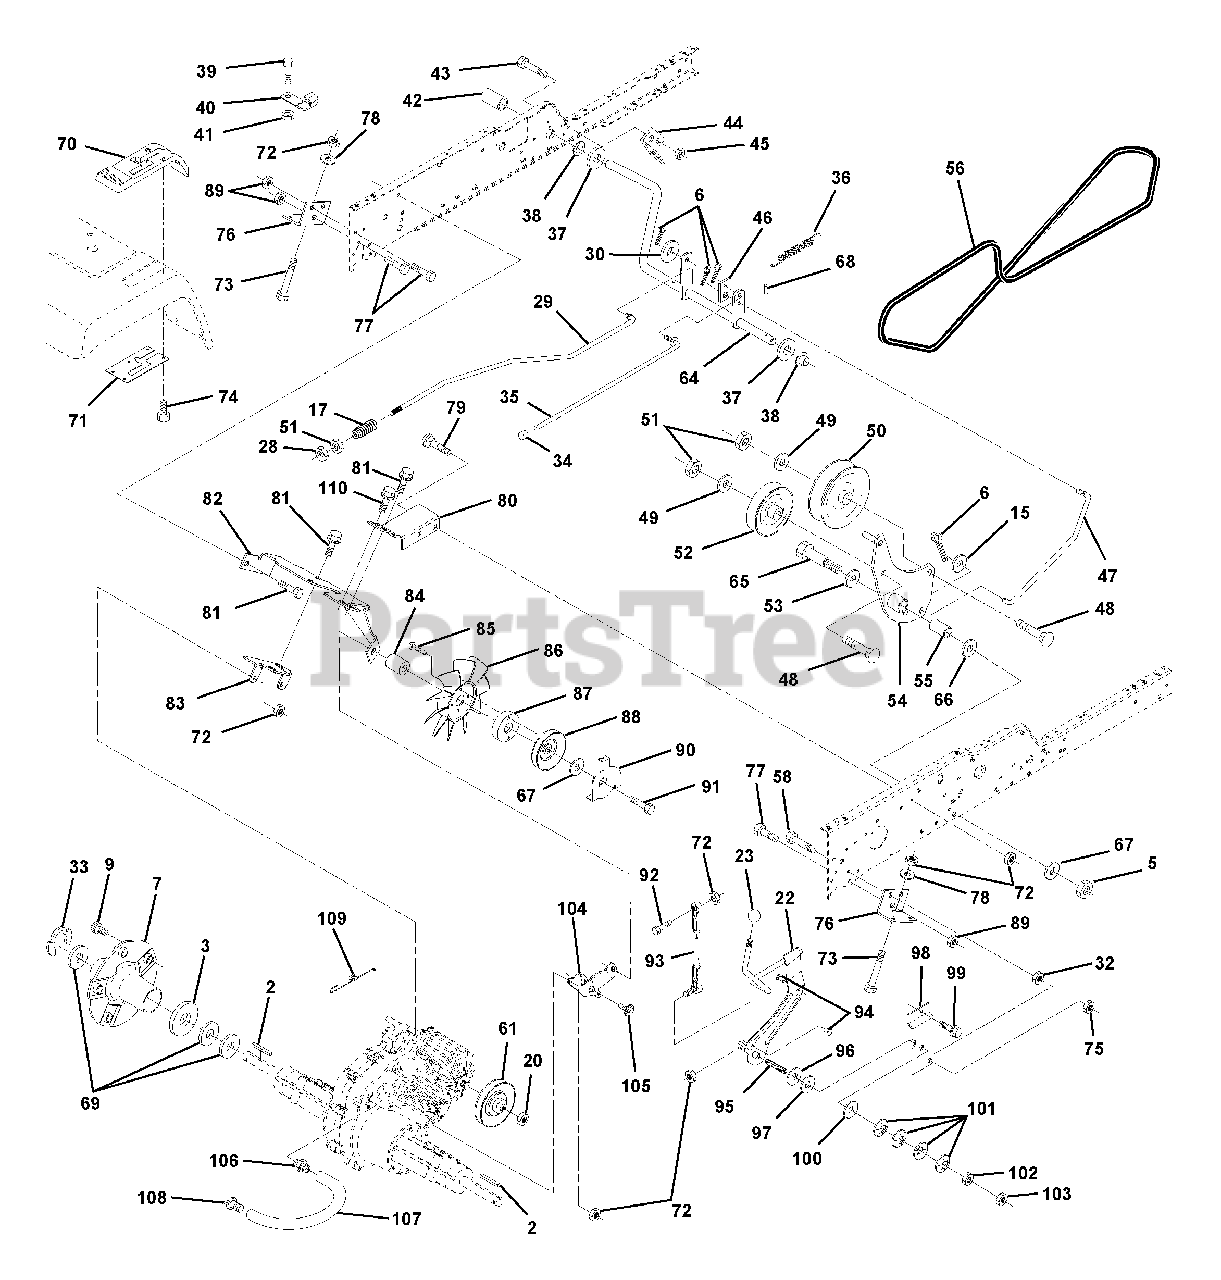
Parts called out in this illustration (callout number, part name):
2	Key 1/4 x 2.5
3	Washer Thrust Axle Harden
5	Nut Crownlock 3/8-16
6	Pin Cotter 1/8 x 3/4
7	Wheel Hub Asm.
9	Bolt Hub
15	Washer 13/32 x 13/16 x 16 Ga.
17	Spring Rod Brake
20	Nut Hex Jam Toplock 1/2-20
22	Shaft Arm Asm
28	Nut, Hex Jam 3/8-16
30	Washer 13/32 x 1 x 16 Ga
32	Nut Hex 7/16-14
34	Cap Plunger
35	Rod Parking Brake
36	Spring Drive Ground
37	Washer 25/32 x 1-1/4 x 16 Ga.
39	Screw Fin #10-24 x 1
40	Actuator Interlock Switch
41	Nut Lock #10-24
42	Cover Pedal
43	Bolt Hex Head 1/4-20 x 3/4
44	Bracket Interlock
45	Nut Lock W/Insert 1/4-20
46	Retainer Spring
47	Clutch Rod
48	Bolt Carriage 3/8-16 x 1-3/4 Gr. 5
49	Washer 13/32 x 7/8 x 13 Ga
50	Pulley Idler Flat
51	Nut Lock Hex 3/8-16
52	Pulley Idler Grooved
53	Washer Hartdened
54	Clutch Arm Asm
55	Bearing, Idler
58	Bolt Fin Hex 7/16-14 x 1-1/2
61	Pullery Transaxle
64	Shaft Asm Brake Parking Clutch
65	Bolt Shoulder
66	Washer Hardened
67	Washer 13/32 x 13/16 x 12 Ga
70	Console Hydro Fender
71	Plate Console Shift
72	Locknut Hex W/Washer Insert
73	Bolt Fin Hex 5/16-18 x 3
74	Screw, Hex Wsh Hi-Lo 1/4-1/2
75	Nut Lock Hex 7/16
76	Bracket Transaxle
77	Bolt Fin Hex 7/16-14 x 1
78	Washer 11/32 x 3/4 x 12 Ga.
79	Bolt Carriage 5/16-18 x 5/8
80	Bracket Torque RH
81	Screw Thdrol 3/8-16 x 3/4
82	Bracket Mount Torque/Fan
83	Strap Torque Mid
85	Screw #10-24 x 1-1/4
86	Fan 7" Hydro
87	Adapter Fan
88	Pulley Idler
89	Nut, Crownlock 7/16-14
90	Keeper Belt
91	Screw Thdrol 3/8-16 x 2-3/4
92	Bolt Fin Hex 5/16-18 x 1.75
93	Link Shift Asm
94	Fastner Christmas Tree
95	Screw Set 5/16-18 x 1.75
96	Washer Nickel Plated
97	Bearing Trust
98	Bracket Shift
99	Screw Thdrol 3/8-16 x 1-1/2
100	Washer Compression
101	Washer Bellville
102	Nut Hex Nylok
103	Nut Hex Jam 5/16-18
104	Bracket Idler
105	Screw Tap 1/4-20 x 1/2
106	O-Ring Asm. Hydro Gear
107	Line Fuel Hydro
108	Cap Vent
109	Spring Return Brake
110	Screw, Hinge
